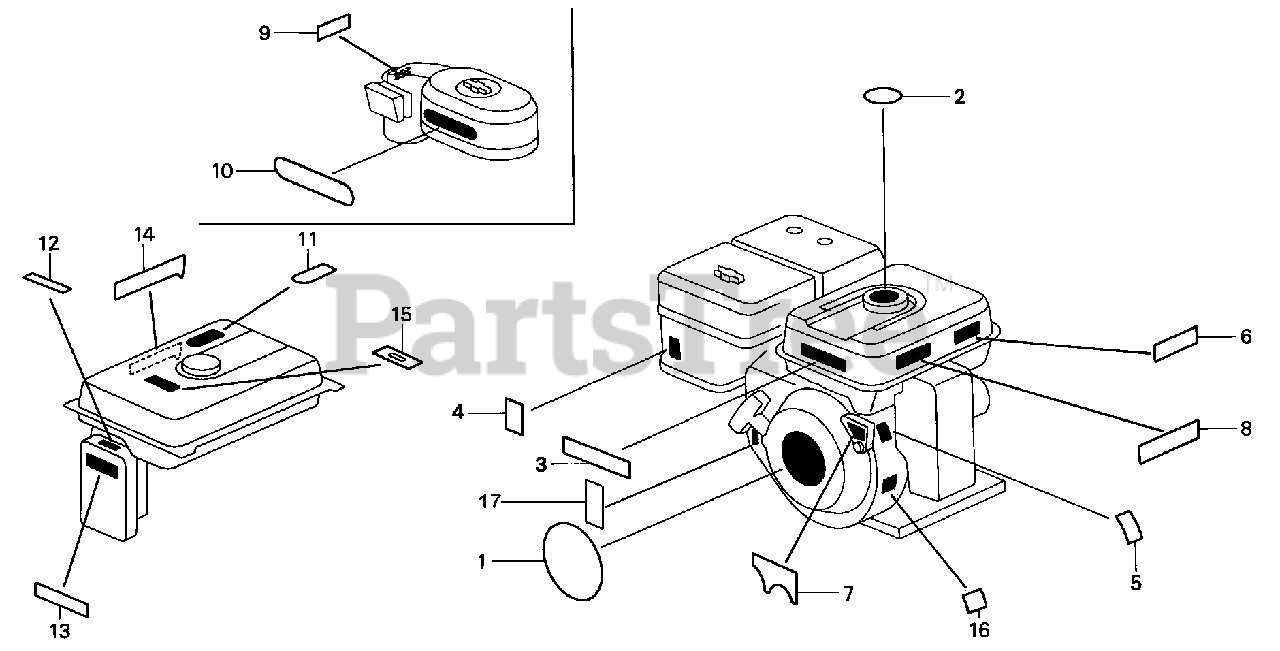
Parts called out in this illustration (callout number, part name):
1	EMBLEM (INTERNAL)
2	MARK, CAUTION (EXTERNAL)
3	LABEL, CAUTION
4	MARK, CHOKE (EXTERNAL)
5	LABEL, SPECIFICATION (EXTERNAL)
6	MARK, OIL ALERT (GERMAN)
7	MARK, OIL ALERT (EXTERNAL)
8	MARK, OIL ALERT (E)
16	MARK, OIL ALERT (FRENCH)
